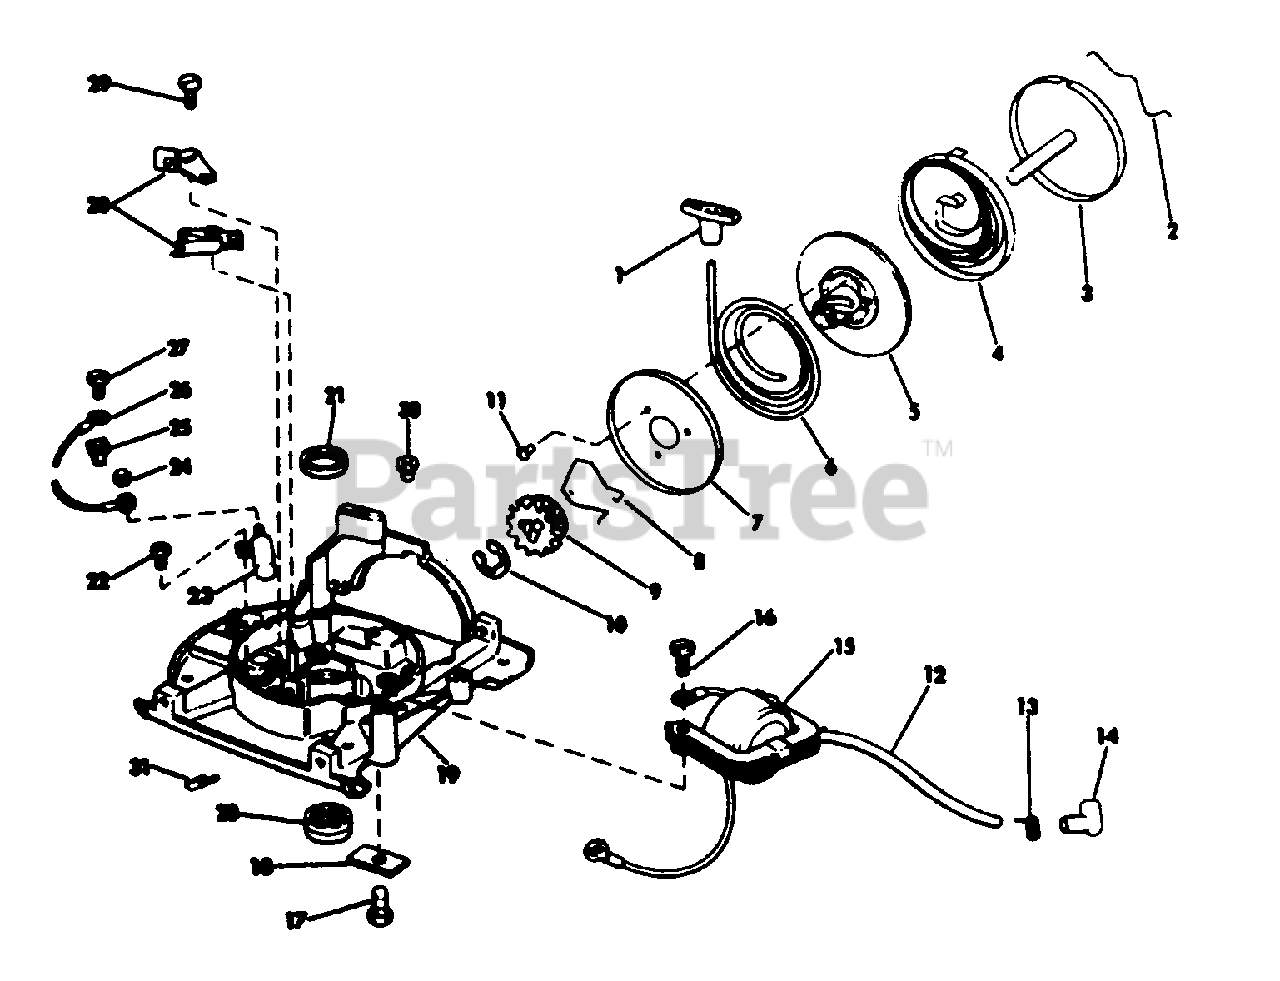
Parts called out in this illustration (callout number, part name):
1	Handle-Starter
2	Spring-Starter Rope Retainer
3	Spring-Cup-Pin Assy.
4	Spring-Starter
5	Pulley-Starter
6	Rope-Starter
7	Plate-Starter Pulley
8	Spring-Starter Pinion
9	Pinion-Starter
10	Retainer-Push-On
11	Screw-Threaded Cutting Starter
12	High Tension Lead Assy.
13	Terminal-Spring
14	Cover-Rubber
15	Coil & Lamination Assy.
16	Scr.-Lamination Mtg.
17	Scr.-Starter Attach.
18	Clamp-Starter Pin
19	Arm. Pl., Bearing & Oil Seal Assembly
21	Oil Seal
22	Scr.-Cond. Mtg.
23	Cond. & Nut Assy.
25	Grommet-Nylon
26	Terminal & Lead Assy.
27	Scr.-Shut-Off Switch
28	Brkr. Base & Arm Assy.
29	Scr.-Breaker Base
30	Grommet
